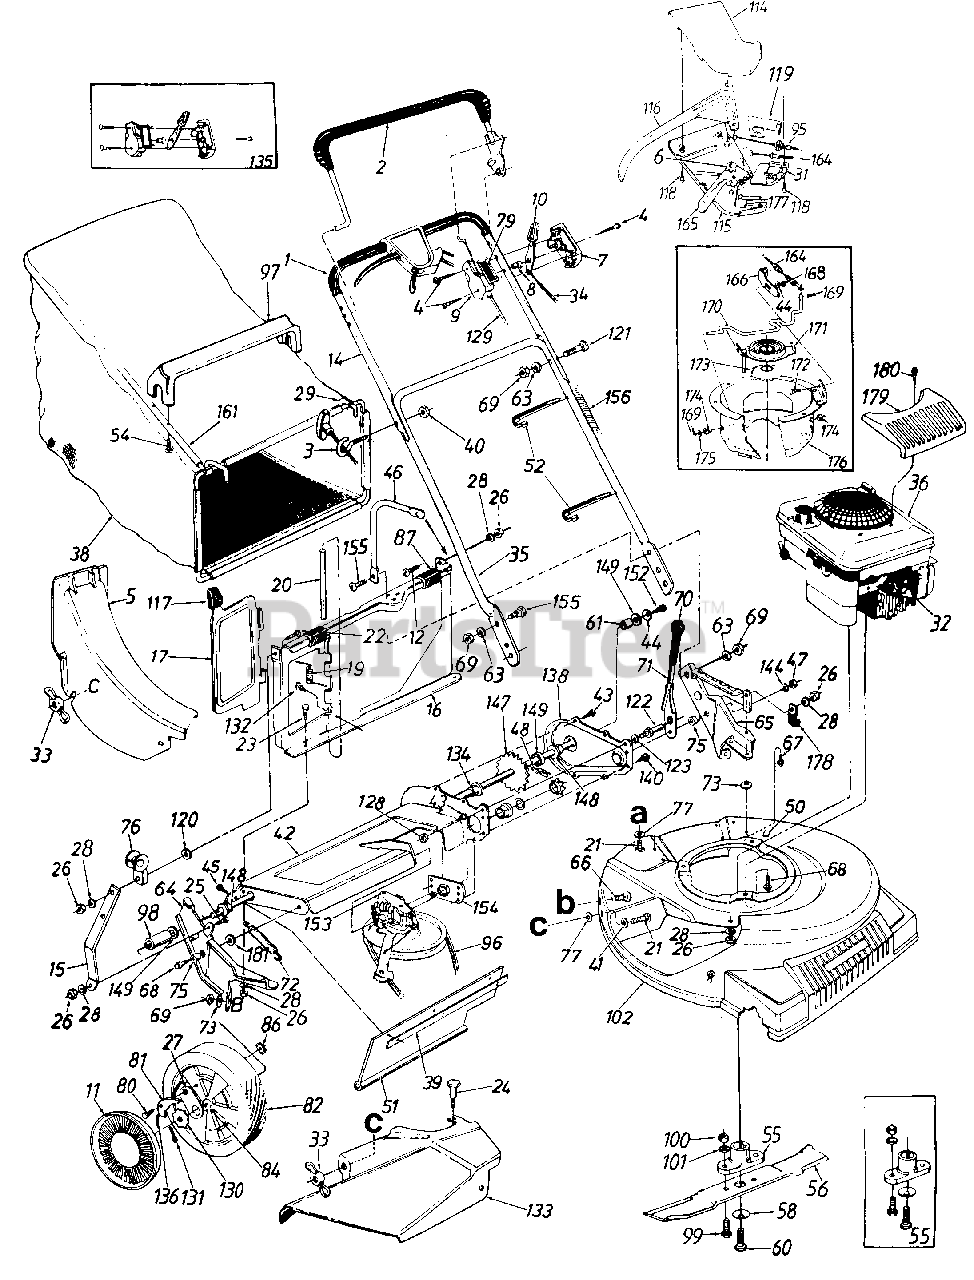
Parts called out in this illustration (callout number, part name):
1	Grip
2	Control Handle Ass'y. L.H.
3	Rope Guide
4	Truss Mach. Scr. #12 x 1.50" Lg.
5	Rear Discharge Chute Ass'y.
6	3 Tooth Rack Gear Insert
7	Control Panel Half
8	Control Disc Pin
9	Clutch Panel Half
10	Throttle Control Lever
11	Hub Cap
12	Truss Mach. Scr. 1/4-20 x .62" L9-t
14	Upper Handle
20	Pivot Pin
21	Carriage Bolt 1/4-20 x .62"
22	Truss Mach. Scr. 1/4-20 x .75" Lg.
23	Hex Bolt 1/4-20 x .5" Lg.
24	Shoulder Bolt Special
25	Hex Bolt 1/4-20 x .62" Lg.
26	Hex Nut 1/4-20 Thd.
27	Pawl Plate
28	L-Wash. 1/4" I.D.
31	S.P. Control Cover
32	Spark Plug Insulator
33	Wing Nut
34	Throttle Control Wire 61
35	Lower Handle
36	Engine
38	Grass Bag
39	Retaining Strip
40	Hex L-Nut 1/4-20 Thd.
41	Fl-Wash. .344" I.D. x .62"
44	Bell-Wash. 1/4" I.D.
45	Hex AB-Tap Scr. 1/4 x .62"
46	Catcher Panel Support Arm
47	Hex Patch L-Nut 3/8-24 Thd.
48	#48 Chain .500" Pitch x 30 Links
51	Rear Flap 3.75" x 17.30" Lg.
52	Cable Tie
54	Hex AB-Tap Scr. #12 x 1.25" Lg.
55	Blade Adapter Kit
56	21" Blade
58	Bell-Wash. .46" I.D.
60	Hex Bolt 7/16-20 x 1.5"
61	Spacer.513" I.D.
63	L-Wash. 5/16" I.D.
64	R.H. Handle Wheel Brkt. Ass'y.
65	L.H. Handle Wheel Brkt. Ass'y.
66	Carriage Bolt 5/16-18 x .62"
67	Hex B-Tap Scr. 5/16-18
68	Hex TT-Tap Scr. 3/8-16
69	Hex Nut 5/16-18 Thd.
71	Height Adj. Lever
72	Extension Spring 3.80" Lg.
73	Bell-Wash. 5/16" I.D.
75	Shld. Spacer .5" Dia.
76	Rope Guidet
77	Bolt Retainer 1/4 x .50" O.D.
79	Control Label
80	Shld. Scr. .342" Dia. x .268
81	Pawl
82	Wheel Ass'y. Comp. Rear
84	Sleeve Bearing 1/2" I.D.
86	Flat Nut 1/4-20 Thd.
87	Panel Clip
95	S.P. Cable 50" Lg.
96	"V"-Belt
97	Bag Handle
98	Sleeve .526" I.D.
99	Hex Bolt 3/8-24 x 1.0" Lg.
100	Hex Nut 3/8-24 Thd.
101	L-Wash. 3/8" I.D.
115	Self-Propelled Control Cover
116	Control Lever
117	Door Grip
118	Fl-"C"-Sunk Hd. Tap Scr. #10 x .75" Lg.
119	6-Speed Rack Cable Brkt.
120	Fl-Wash. .285" I.D. x 1.25" O.D.
121	Curved Carr. Bolt 5/16-18 x 1.38" Lg.
122	Shld. Pin 1.43" Lg.
123	L-Wash. 3/8" I.D.
128	Hex Jam Nut 3/8-24 Thd.
129	Control Cable 46"
130	Ratchet Wheel 1.62" O.D.
131	Cotter Pin 1/8" Dia. x 1"
132	Hex B-Tap Scr. #10 x .38" Lg.
133	Side Chute Deflector Ass'y.
134	Hex Flange Bearing
135	Kit Control Housing Comp.
136	Spring Nylon
144	Fl-Wash. .385" I.D. x .87"
147	Rear Shaft Ass'y. 21.94" Lg.
148	Hex Flange Brg. .506" I.D.
149	Fl-Wash. .531" kD. x .930
152	Hex Bolt 1/4-20 x .62" Lg. (Grade 5)
153	Transmission Comp.
155	Truss Mach. Scr. 5/16-18 x 75" Lg.
156	Plastic Tubing
164	Spd. Control Cable 50" Lg.
165	6-Spd. Shift Lever
169	Cot-Pin 3132" Dia. x .75" Lg.
170	Shift Rod
171	Movable Pulley Half Ass'y.
172	Carr. Bolt 1/4-20 X .5" Lg.
173	Splined Pulley Half
174	Flanged Bushing
175	Fl-Wash. .328" I.D. x .68" O.D.
176	Cable Mtg. Brkt. Ass'y.
177	Shift Lever Spring
178	Clamp
179	Engine Cover
180	Truss Hd. AB-Tap Scr. #6 x .62" Lg.
181	Fl-Wash. .383" I.D. x 1" O.D.
